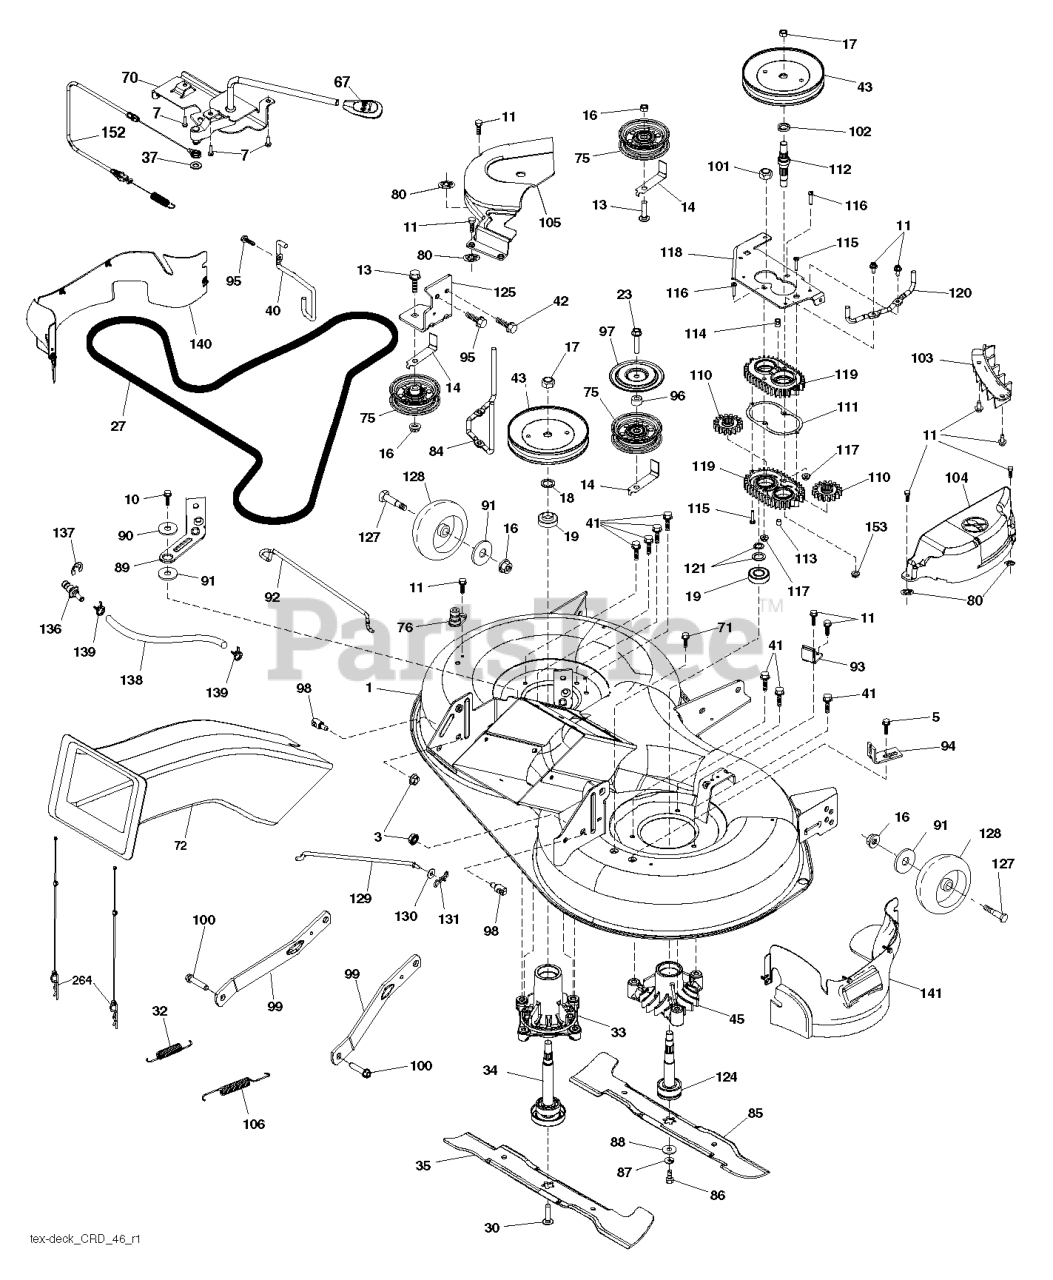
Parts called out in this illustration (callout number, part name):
1	DECK.WELDMENT.97.TEX.498
3	NUT LOCK HEX FLANGE 5/16-18
5	BOLT.5/16HEX.WHS.HD
7	SCREW.#10 X 0.750.BOS
10	SCREW 3/8-16X1
11	SCREW.1/4-20X5/8
13	BOLT.3/8-16X1.50
14	KEEPER, BELT IDLER
16	NUT LOCK FLG 3/8-16 UNC
17	NUT.FLANGE.LOCK.TOP
18	WASHER.SPACER.MANDREL
19	BEARING.MANDREL.TOP.EXTENDED
23	SCREW LT
27	BELT V-BELT DRIVE
30	SCREW.SEMS.7/16-20X1.HEX.HEAD
32	SPRING RETURN
33	RP.HOUSING.MANDREL.4PT.
34	SHAFT ASM.MNDRL.N/GREASEABLE
35	BLADE.3N1.LH.CRD.97
37	WASHER
40	KEEPER BELT ENGINE LH
41	BOLT.HEX.WASHR.HED.313-18X1.19
42	SCREW
43	PULLEY.MANDREL.5.438.PD
45	HOUSING.MANDREL.44/46" VENT
67	HANDLE.CLUTCH.CABLE.LT
70	CLUTCH.ASM.MANUAL.YT.PREDATORQ
71	SCREW 3/8-16X1/2
72	CHUTE.SLOTTED.HOLES.TEX.CRD.II
75	FLAT IDLER PULLEY
76	1/2" BARB.DECK.WASHOUT.PORT
80	PALNUT 1/4
84	KEEPER.BELT.MANDREL.PULLEY
85	BLADE.3N1.RH.CRD.97
86	BOLT.3/8-24X1.25GR8. LHTHRD
87	SLW 3/8 STD
88	WASHER.BLADE
89	ARM.BRAKE.97.LH
90	SPACER.RETAINER
91	WASHER
92	ROD ROD BRAKE
93	ARM.BRAKE.97.RH
94	BRKT.CLUTCH.CABLE
95	SCREW, 3/8-16X3/4
96	SPACER
97	PROTECTOR
98	STUD.FASTNER.W/ANTI-ROTATE
99	ARM.SUSPENSION.MOWER.R
100	BOLT.SHOULDER
101	NUT.CROWNLOCK.9/16 -18.UNC
102	SPACER BEARING
103	GUARD GUARD FRONT VENT
104	97.CRD.RH.MANDREL.COVER
105	MANDREL MANDREL COVER LH
106	SPRING.BRAKE.RETURN.38"
110	CRD.SPUR.GEAR
111	GASKET GASKET GEARCASE
112	SHAFT SHAFT. CRD GEARCASE ADAP
113	PLUG PLUG OIL
114	VENT.BREATHER.1/8 NPT
115	SCREW
116	BOLT.CARIGE.SS.1/4-20X1.75GR5
117	NUT T
118	ARM ARM CLUTCHING
119	GEARCASE GEARCASE SUBASM
120	BRACKET KEEPER BELT RH
121	WASHER WASHER
124	MANDREL SHAFT NON/GREASE
125	BRACKET
127	BOLT.SHOULDER.3/8-16X3-5/8.
128	WHEEL.GAUGE.RALLY
129	ROD ROD. SWAY CRD GEN II
130	WASHER
131	PIN.COTTER.5/16.BOW TI
136	PLUG WASHOUT PORT HOOKUP
138	HOSE.3/8ID.BULK.12"
139	HOSE.3/8.CLAMP (2 2)
140	GUARD.ASSEMBLY.97.LH.FRENCH
141	GUARD.ASSEMBLY.97.RH.FRENCH
152	CABLE CABLE CLUTCH MANUAL W/S
153	NUT HEXAGON 9/16-18 G2 ZPB LOC
264	RETAINER.ASM.UPPERCHUTE.CRD2.5
